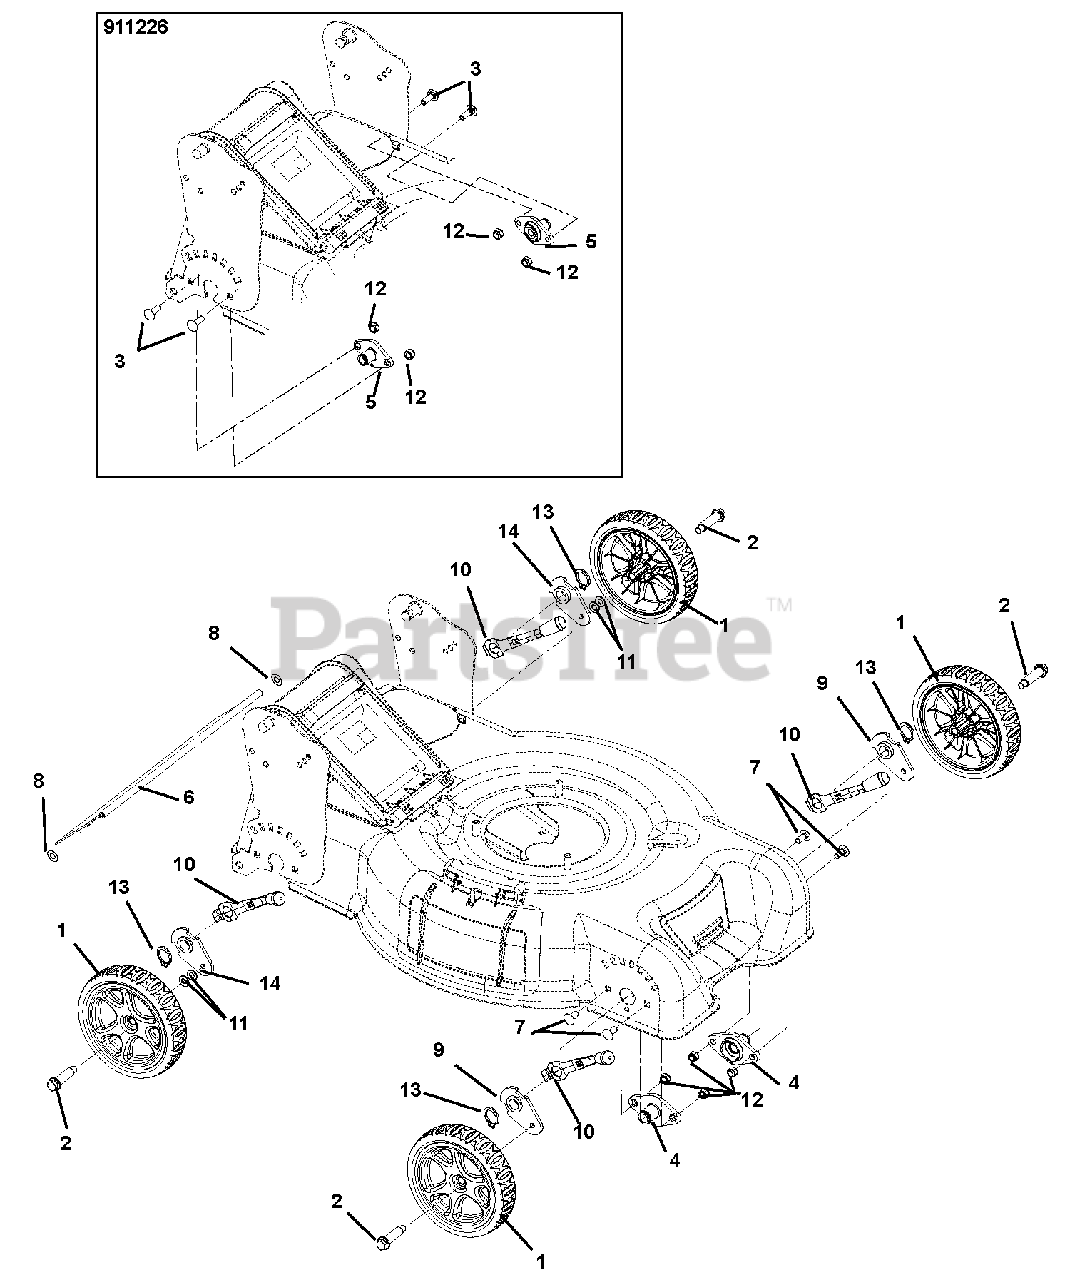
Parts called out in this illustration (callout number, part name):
1	Wheel, 8.5" WBLM Assembly
2	Bolt, Wheel Shoulder
3	Bolt, Round Head Square Neck .31-18 x 1.00 Grade 5
4	Wheel Mount Hub (911220, 221)
5	Wheel Mount Hub (911222, 226)
6	Guard, WBLM
7	Bolt, Round Head Square Short Neck .31-18 x .75 Grade 5
8	Retainer, .38 Push-On
9	Plate, Front Wheel Mount
10	Height of Cut Lever
11	Washer, Flat Steel .406 x .812 x .065 (911222, 226)
12	Nut, Locking Top Flange .31-18
13	Ring, Retaining - External .689 x .077
14	Plate, Rear Wheel Mount
